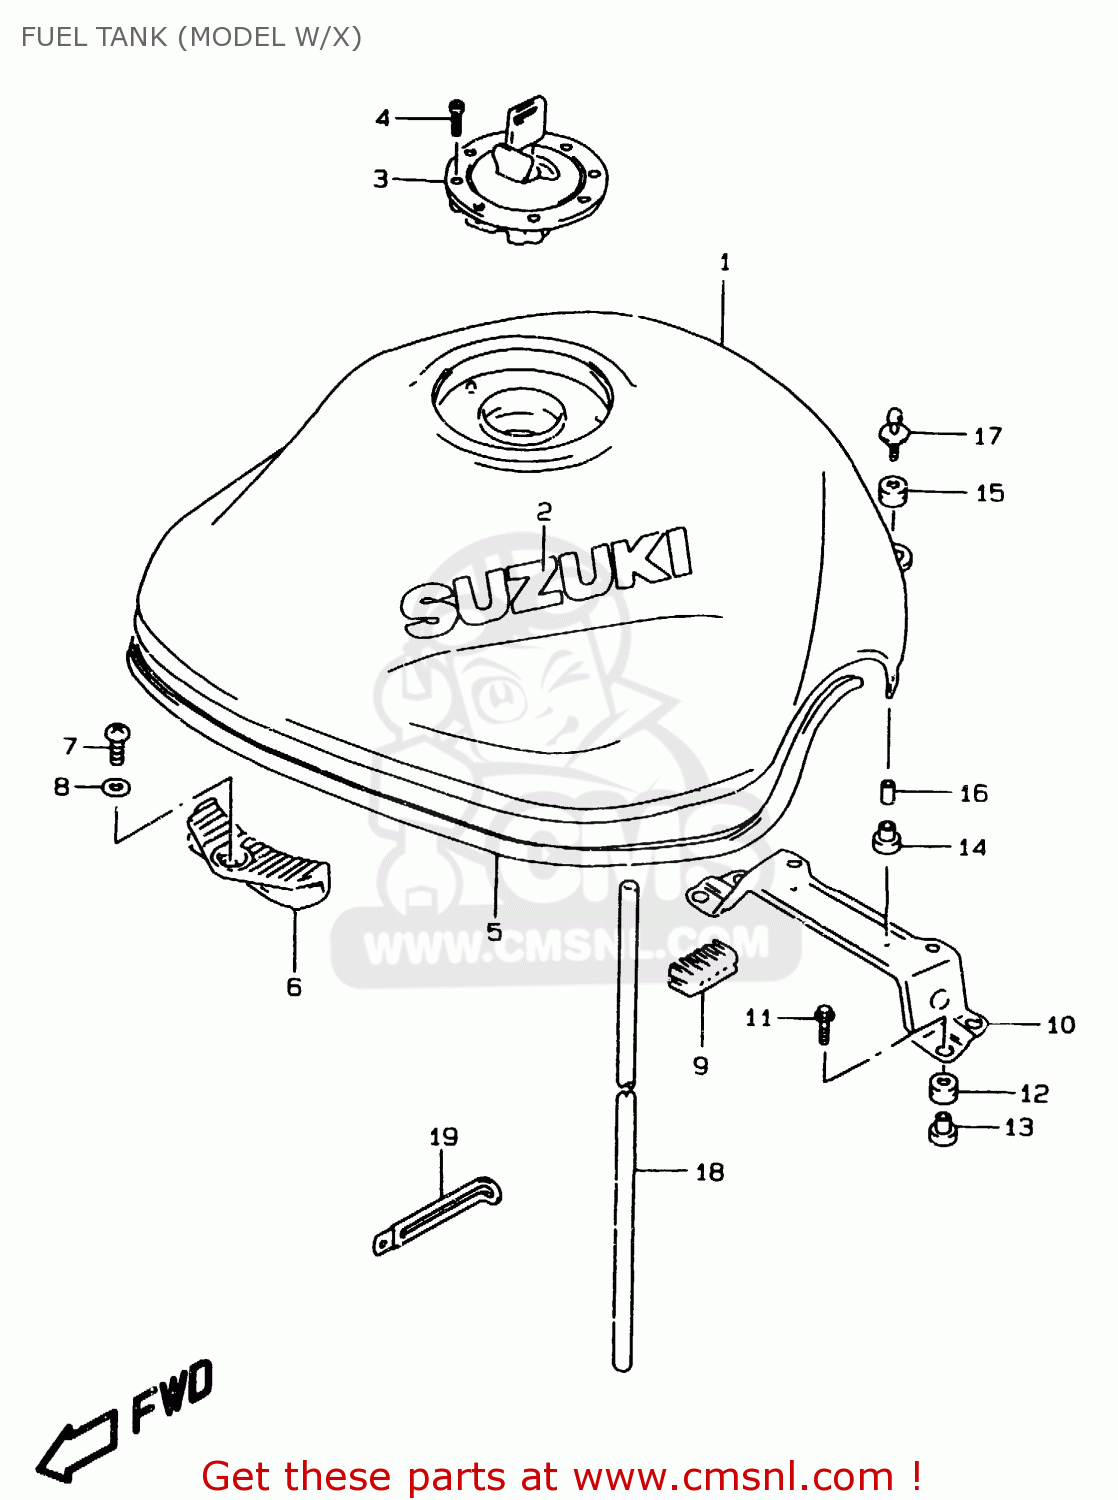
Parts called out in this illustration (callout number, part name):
1	TANK ASSEMBLY,FUEL
2	EMBLEM,FUEL TANK
3	CAP SET,FUEL TANK
4	BOLT(5X20)
5	MOLDING
6	CUSHION,FUEL TANK FR
7	SCREW
8	WASHER
9	CUSHION,SEAT(40X20X15)
10	BRACKET,FUEL TANK RR
11	BOLT(6X25)
12	CUSHION
13	WASHER
14	CUSHION
15	CUSHION
16	SPACER(6.5X9X18)
17	BOLT(6X30)
18	HOSE(7X10.2X2000)
19	CLAMP(L:97)
